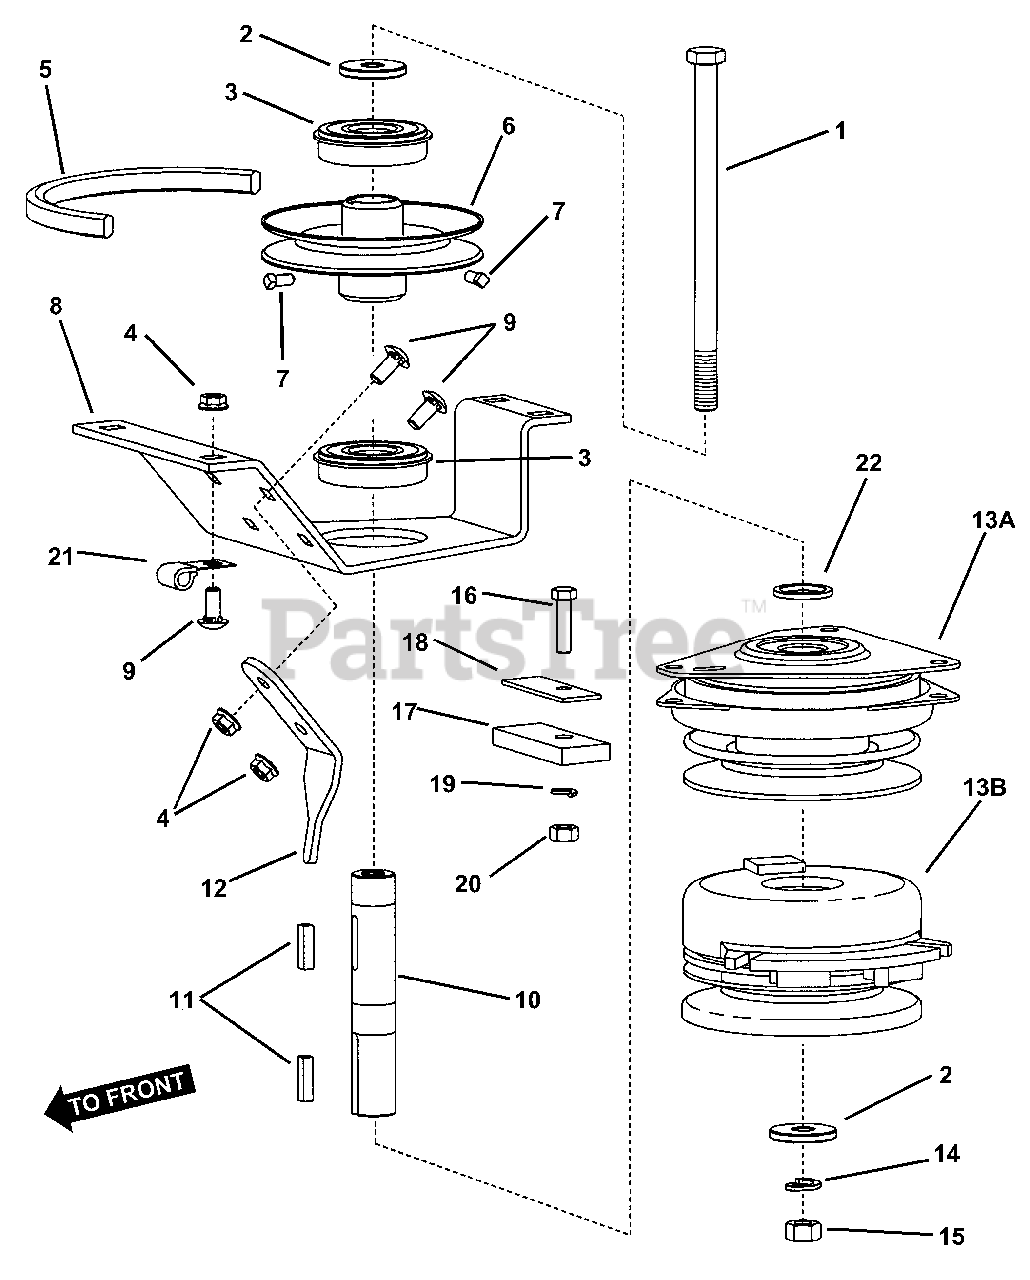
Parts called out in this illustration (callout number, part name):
1	SCREW, 7/16-20 x 8" Hex Head Cap
2	WASHER, 7/16 x 1" O.D. Flat
3	BEARING, 6305 w/Snap-Ring
4	NUT, 5/16-18, Grade 5
5	V-BELT, 5L Cogged 50.170" effective length
5	V-BELT, 5L Cogged 49.44" effective length (48" Model)
6	PULLEY, Jackshaft
6	PULLEY, Jackstaff (48" Model)
7	SETSCREW, 1/4-20 x 1/2" w/Patch
8	SUPPORT, Jackshaft
9	BOLT, 5/16-18 x 3/4 Carriage, Grade 5
10	JACKSHAFT
11	KEY, 1/4 x 1" Square
12	BRACKET, Anti-Rotate
13A	CLUTCH, Electric (Ogura) (12 V, 4 OHM)
13B	CLUTCH, Electric (Warner) (12V, 3.3 AMP, 3.5 OHM)
14	WASHER, 7/16" Split Lock
15	NUT, 7/16-20 Hex, Grade B
16	SCREW, 5/16-18 x 1-1/4", Hex Head Cap, Grade 5
17	BUMPER, Electric Clutch
18	WASHER, Rectangular Steel
19	WASHER, 5/16" Split Lock
20	NUT, 5/16-18, Grade 5
21	CLIP, Wire, 7/16
22	WASHER (Ogura Clutch) (.125" thick)
22	WASHER (Warner Clutch) (.750" thick)
